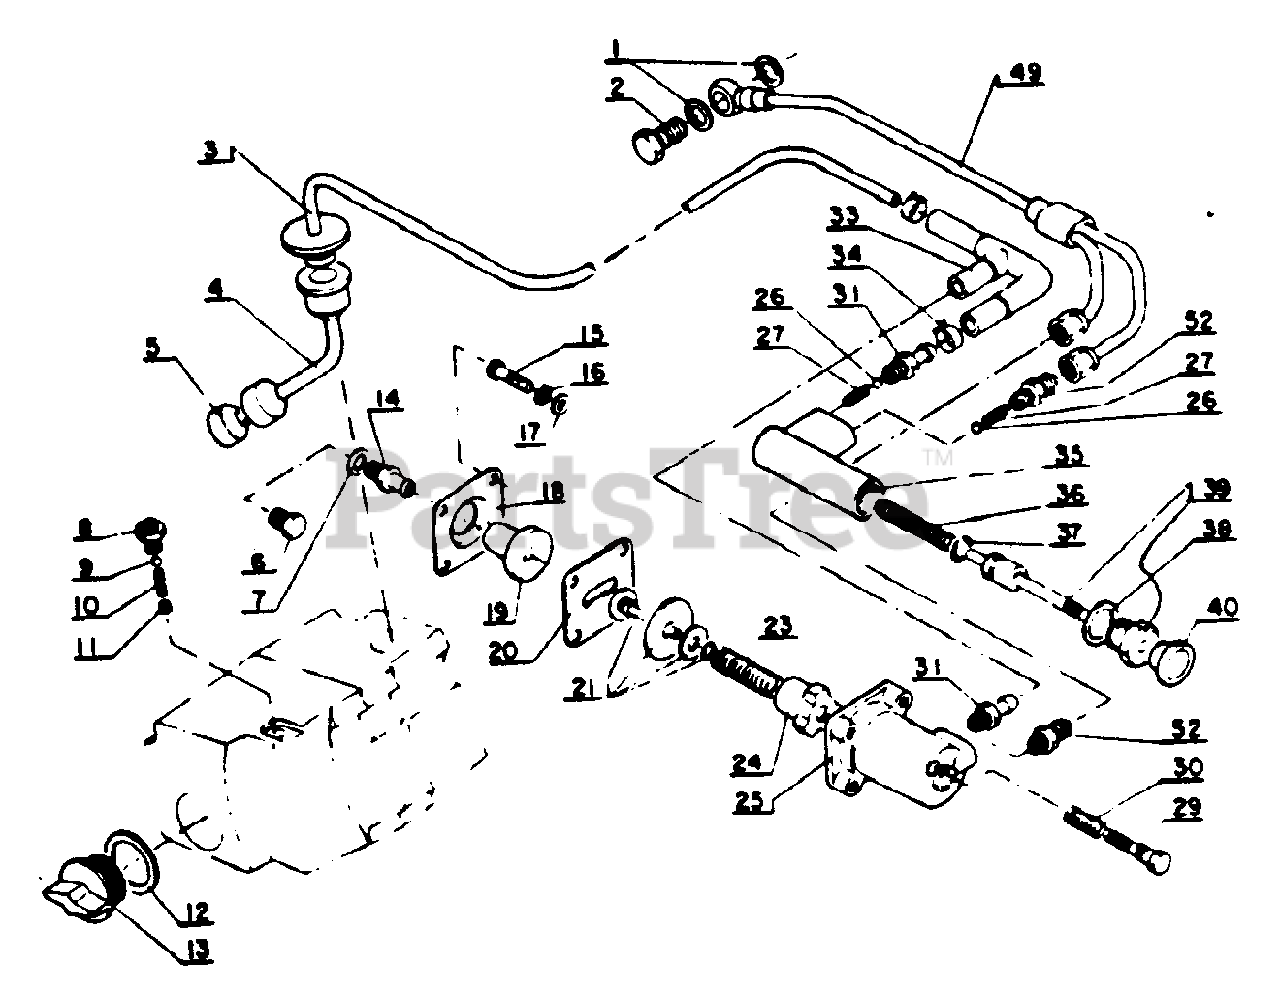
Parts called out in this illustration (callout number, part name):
3	PIPE - OIL
4	PIPE, OIL - INNER
5	FILTER, OIL
8	Nut, air breed
9	VALVE, BALL
10	SPRING, AIR BLEED
11	Plug, air breed
13	OIL TANK CAP
15	SCREW
15	SCREW - 4X15
16	LOCKWASHER - 4
17	WASHER - 4
18	RETAINER
19	CONNECTOR
21	PLUNGER ASSY
23	SPRING, ADJUST
24	CASE, SPRING
25	CYLINDER, OIL
26	VALVE, BALL
27	Valve spring
29	SCREW, ADJUST
30	SPRING
31	CONNECTOR
32	PIPE - OIL
33	PIPE - OIL
34	CLIP
35	BODY, OIL PUMP
36	SPRING, OIL PUMP
37	O-RING
38	LOCKWASHER
39	PISTON, OIL PUMP
40	BUTTON, OIL PUMP
49	PIPE - OIL
52	CONNECTOR
